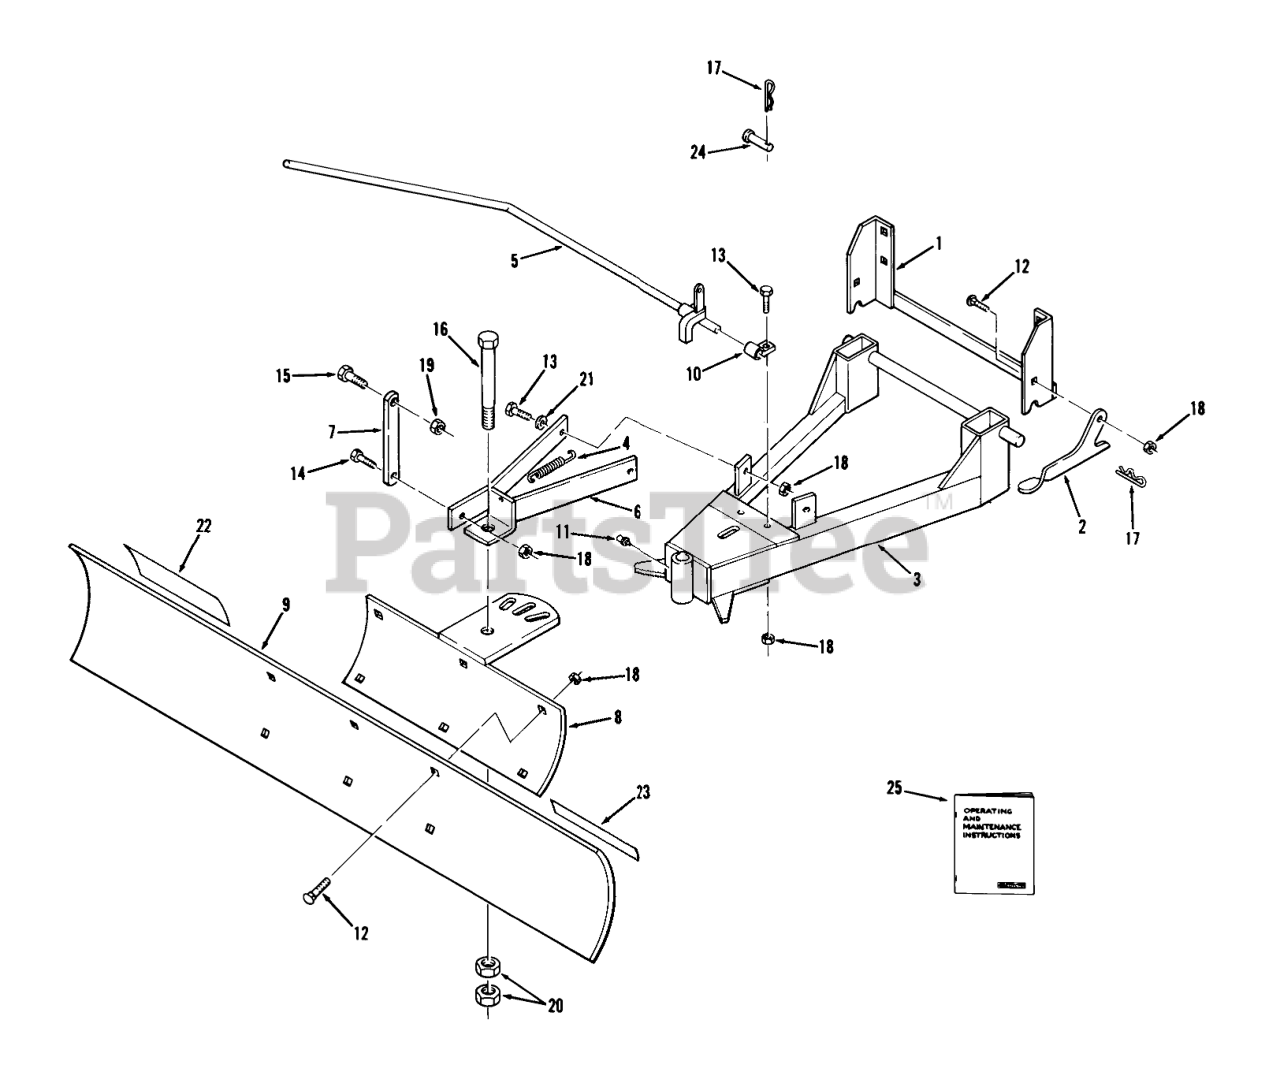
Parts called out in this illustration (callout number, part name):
1	Bracket
2	PLATE-LATCHING
3	"A" Frame Assembly
4	Spring
5	Blade Index & Lock Lever
8	PIVOT&BLADE MT (A R
9	Blade
10	Bushing-Index Lever
11	Zerk
12	Bolt
13	BOLT
14	Bolt
15	Hhcs
16	BOLT 3/4-10X5
17	Hairpin Cotter
18	Nut
19	Eslok Nut
21	Washer
22	Caution Decal
23	DECAL-WHEEL HORSE
25	Operating and Maintenance Instructions
